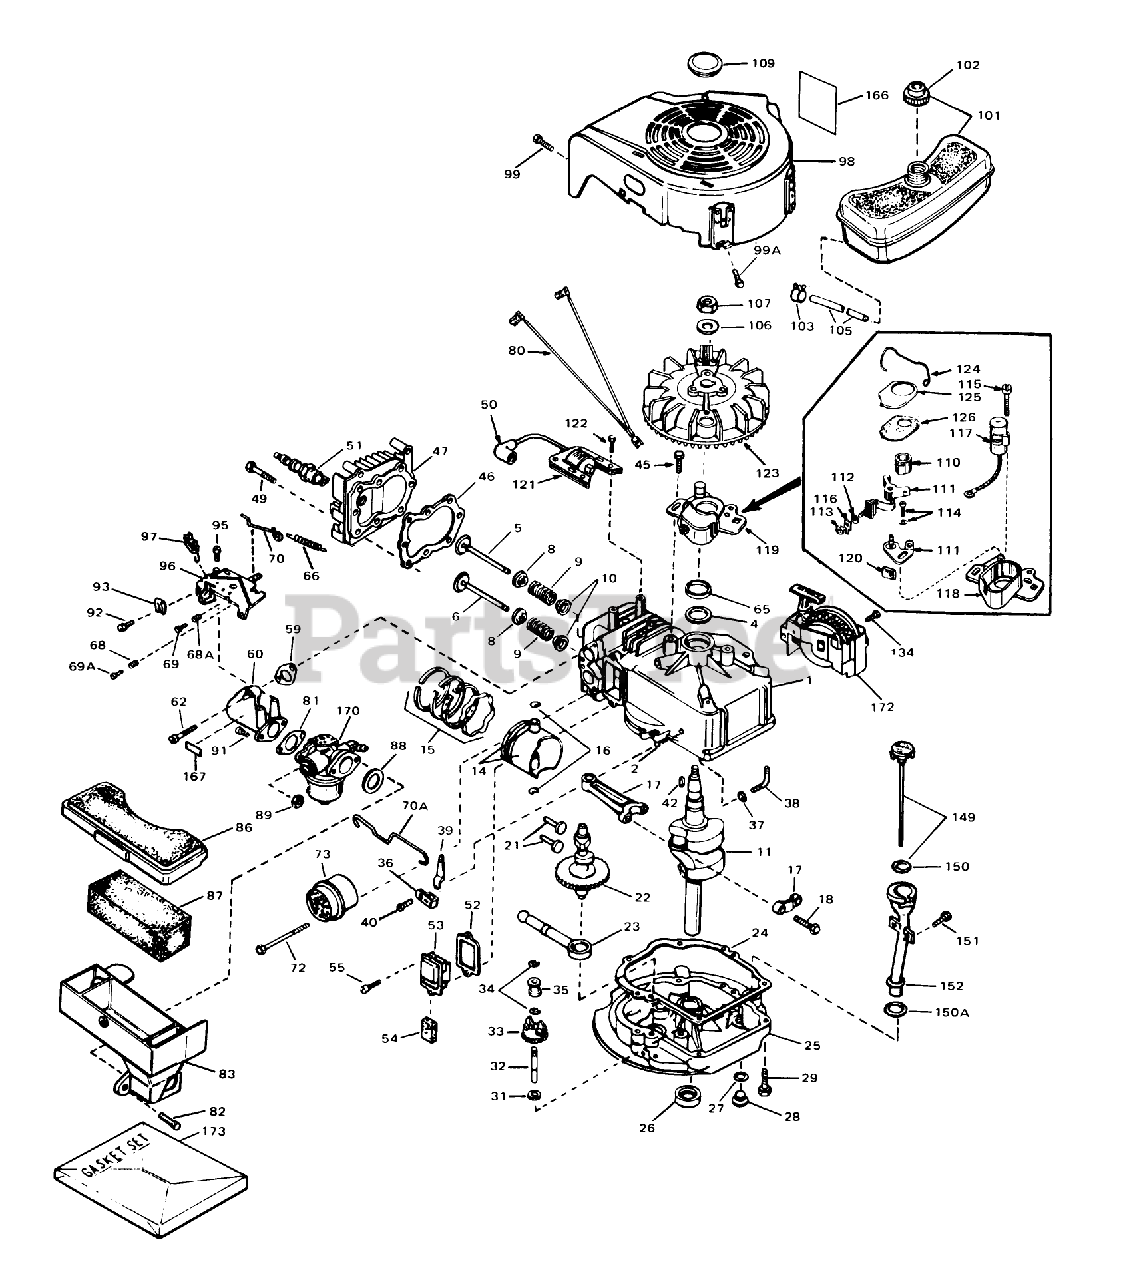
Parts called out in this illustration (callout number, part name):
1	Cylinder Assembly (Incl. Nos. 2 4)
2	Pin-Dowel
4	Seal-Oil
5	Valve, Intake (Incl. Ref. #38, 39 40) (Std.)
5	Valve, Exhaust (1/32" Oversize) (Incl. Nos. 8, 9 10)
6	Valve, Exhaust (Standard) (Incl. Nos. 8, 9 10)
6	Valve, Exhaust (1/32" Oversize) (Incl. Nos. 8, 9 10)
8	Cap-Upper Valve Spring
9	Spring-Valve
10	Cap-Valve, Spring
11	Crankshaft
14	Piston, Pin Ring Assy. (Std.) (Incl. Ref. #15 16)
14	Piston, Pin Ring Assy. (.010 Oversize) (Incl. Ref. #15 16)
14	Piston, Pin Ring Assy. (.020 Oversize) (Incl. Ref. #1516)
15	Piston Ring Set Std.
15	Piston Ring Set .010 O.S.
15	Piston Ring Set .020 O.S.
16	Ring-Retaining, Piston Pin
17	Rod Assy., Connecting (Incl. Ref. #17)
18	Bolt-Rod, Connecting
21	Lifter-Valve
22	Camshaft(Mech.Comp. Release)
23	Oil Pump ASM
24	Gasket, Mounting
25	Flange Assy., Mounting (Incl. Ref. #26thru 30)
26	Seal Oil
27	Gasket-Oil Drain
28	Plug Oil Drain
29	Screw (1/4-20 x 1-1/4)
31	Washer-Flat
32	Shaft-Governor
33	Governor Gear ASM
34	Ring-Retaining
35	Spool-Governor
36	Clamp-Lever, Governor
37	Washer-Flat
38	Rod, Governor (Incl. No. 36)
39	Lever, Governor
40	Screw
42	682488 LB GRASS HI-
45	Screw
46	Gasket-Cylinder Head
47	2025A67 ADD.ASSEMBL
49	Screw (5/16-18x1-1/2)
50	Cover-Spark Plug
51	Plug, Spark (J17LM or equiv.)
51	Plug, Spark (Champion RCJ-8)
52	Gasket Breather
53	Breather Assembly (Incl. Nos. 52 84)
54	Element-Breather
55	Screw
59	Gasket, Intake
60	Pipe, Intake
62	Screw (1/4-20 x 1)
65	Gasket Stator
66	Spring Governor
68	61709/GIL1515A/95-5
68A	Spring-Compression
69	Screw
69A	Screw
70	2035A67 ADD.ASSEMBL
70A	Link-Throttle
72	Screw
73	Muffler Kit (Incl. Ref. #72)
80	Wire Ground
81	Gasket
82	Screw
83	Body, Air Cleaner
86	Cover Air Cleaner
87	Filter-Air Cleaner
88	Gasket-Cleaner, Air
89	Nut and Lock Washer (1/4-28)
92	Screw (10-32 x 3/8)
93	Conduit
95	Screw (10-24 x 9/16)
96	Control Assy.-Remote Speed (Incl. Ref. #69 thru 72 76)
97	Terminal
98	Housing, Blower
99	Screw (10-24 x 9/16)
99A	Screw
101	Tank, Fuel
102	Cap, Fuel
103	Clamp-Line, Fuel
105	Fuel Line
106	Washer-Belleville
107	Nut-Flywheel
109	Plug, Screen
110	Cam-Breaker
111	Breaker Assy.
112	Washer
113	DECAL
114	Breaker Screw
115	Condenser Screw
116	Terminal, Ground
117	Condenser
118	Stator Plate
119	Stator Plate Assy. (incl. Nos. 107, 111 thru 118 120)
120	Felt,Cam Wiper
121	Lamination Coil Assy. (Incl. No. 42)
122	Screw
123	FIywheel
124	Spring Breaker Box
125	Cover-Dust
126	Gasket-Dust Cover
134	Screw (1/2-20x5/8)
149	Dipstick-Oil (Incl. Ref. #112)
150	O-Ring
150A	Gasket
151	Screw (10-32 x 1/2)
152	Tube-Oil Fill
166	Decal, Instruction
167	Decal-Primer
170	Carbu retor (Incl. Ref. #81)
172	Starter-Sidemount
173	Gasket Set
